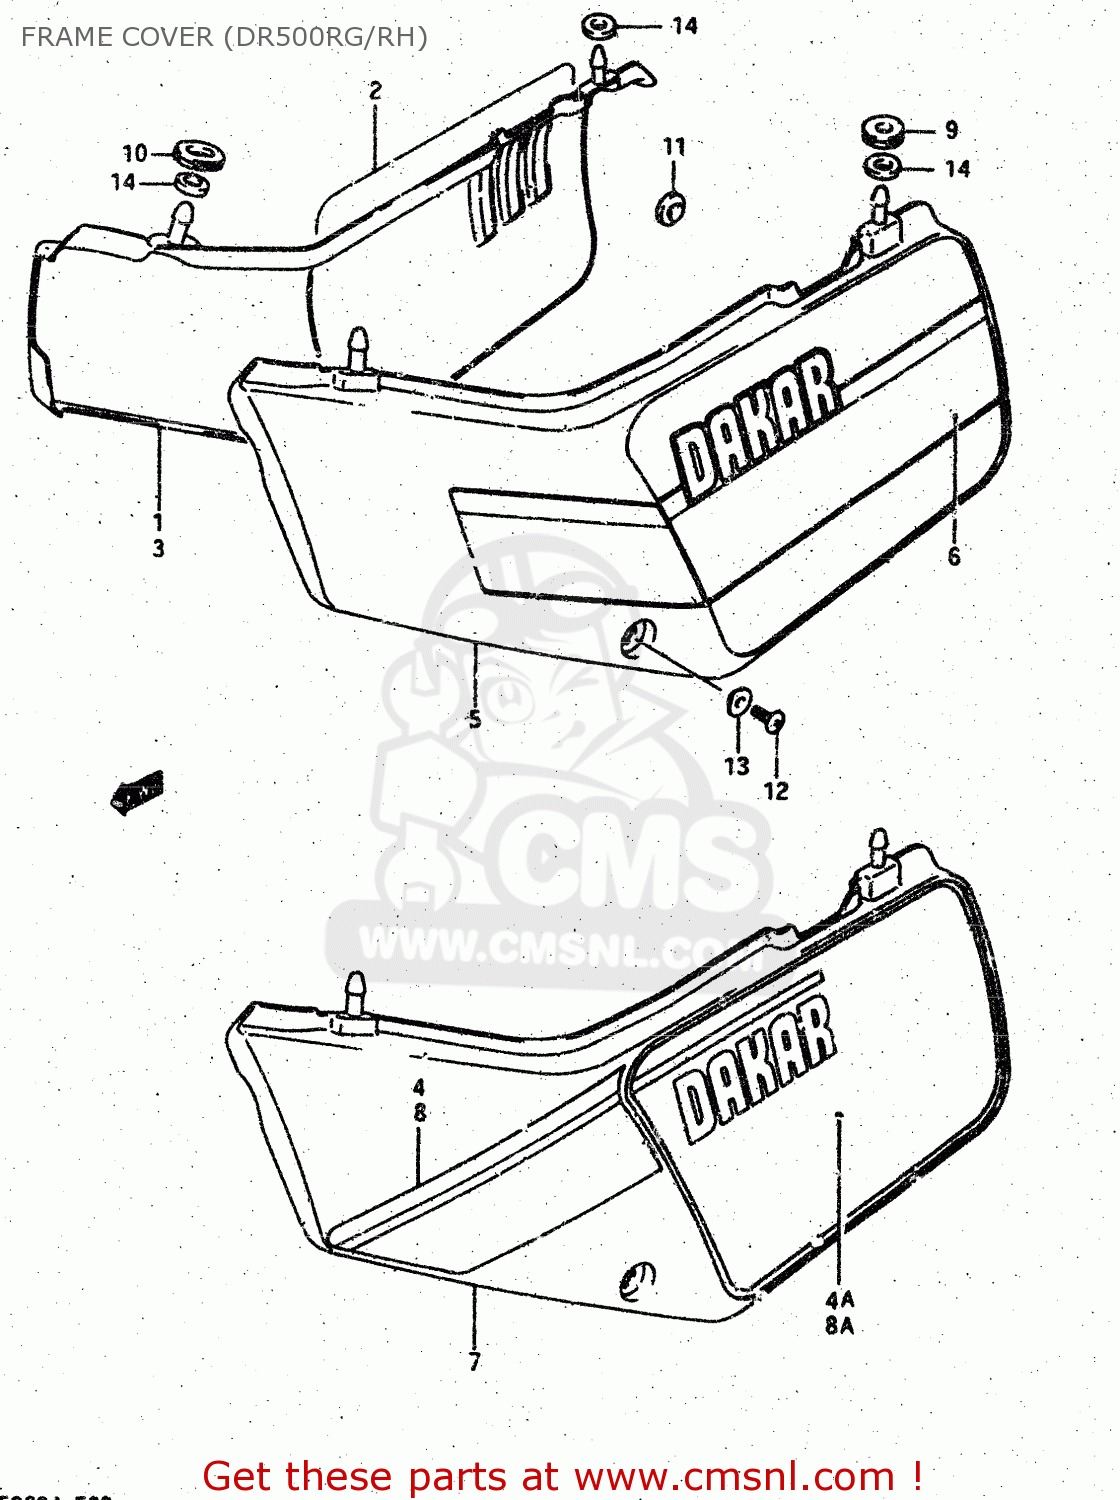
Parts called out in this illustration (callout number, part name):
1	COVER, FRAME RH (WHITE)
2	TAPE SET, FRAME COVER RH
3	COVER, FRAME RH (WHITE)
4	TAPE,FRAME COVER FR,R
4A	TAPE, FRAME COVER REAR RH
5	COVER, FRAME LH (WHITE)
6	TAPE SET, FRAME COVER LH
7	COVER, FRAME LH (WHITE)
8	TAPE,FRAME COVER FR,L
8A	TAPE, FRAME COVER REAR LH
9	CUSHION
10	CUSHION
11	CUSHION
12	SCREW 6X12
13	WASHER
14	CUSHION,SIDE COVER BOSS
